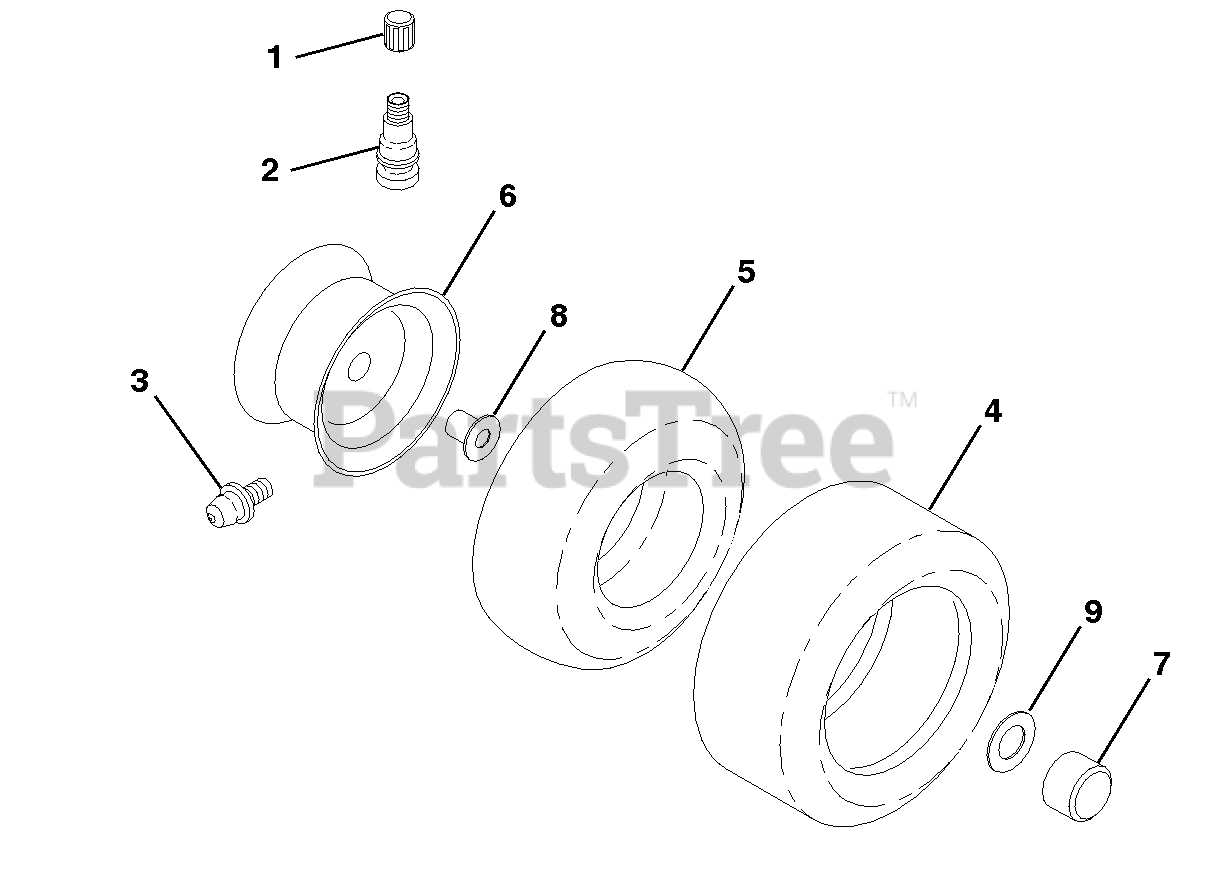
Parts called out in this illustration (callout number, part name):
1	Cap, Valve
2	Stem, Valve
3	Fitting, Grease
4	Tire, Front
4	Tire, Rear
5	Tube, Front
5	Tube, Rear
6	Rim, Front
8	Bearing Flange
9	Washer 25/32 x 1-5/8 x 16 Ga.
